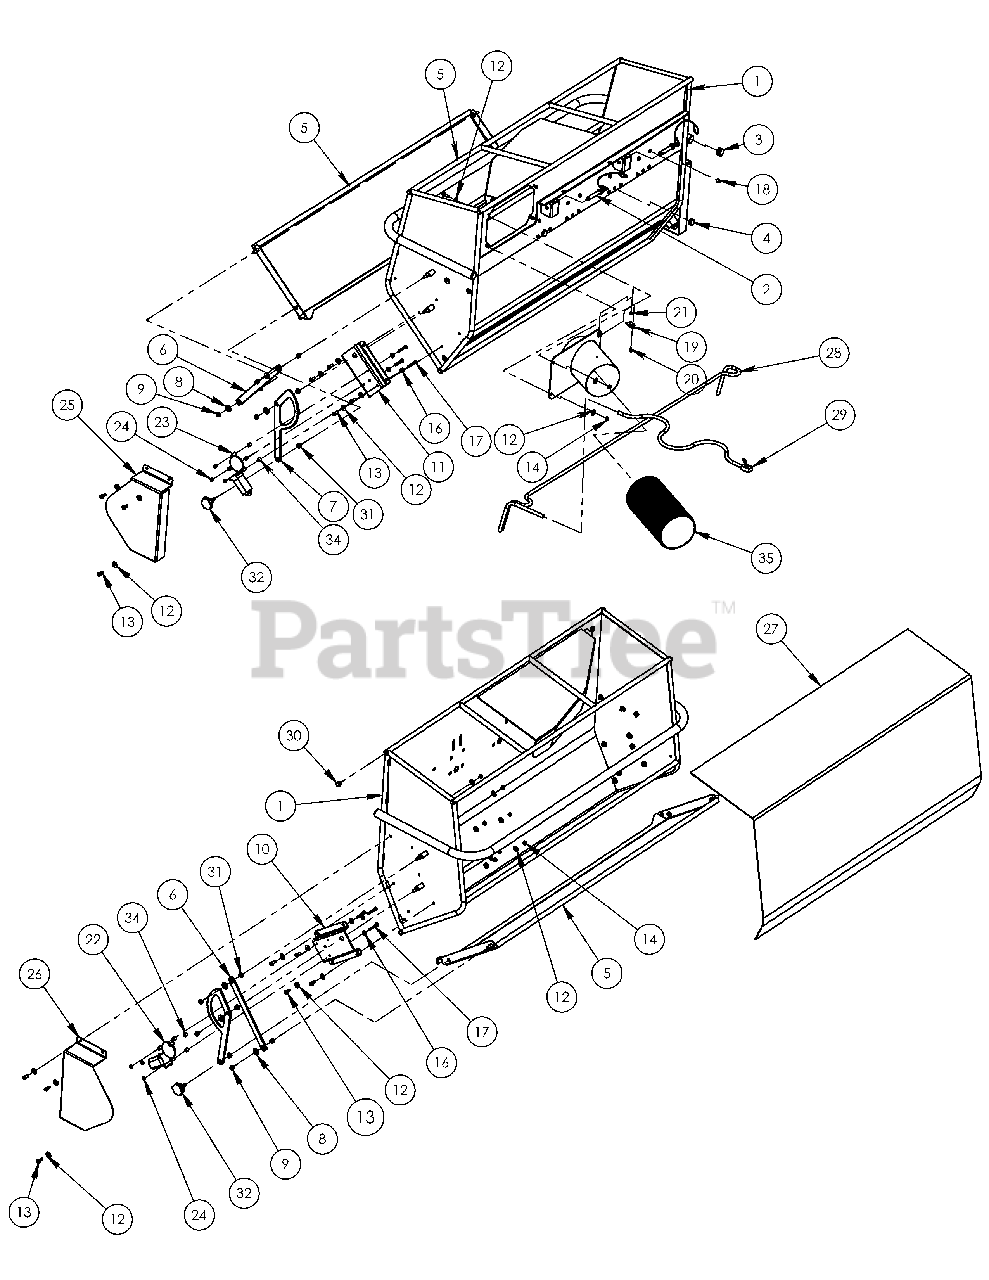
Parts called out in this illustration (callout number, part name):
1	DEDICATED DUMP FRAME 54"
2	1/2 DETENT PIN 2.5" LONG
3	1.25" HOLE PLUG, PLASTIC
4	RUBBER BUMPER
5	GATE ASSEMBLY
6	MASTER LINK
7	DFS ELECTRIC DRIVE RING-GEAR
8	3/8 Washer SAE
9	3/8-16 NYLOCK NUT
10	MOTOR ADAPTER PLATE
11	MOTOR ADAPTER PLATE
12	5/16" Flat Washer
13	CAP SCREW 5/16-18 x .75
14	5/16-18 Nylon Insert Nut
15	6" 3-BAG INLET TUBE
16	1/4" USS WASHER
17	CAP SCREW 1/4-20 x 1 3/4
18	PLUG, HOLE 7/16
19	SPRING CLIP
20	#10 x 3/4 SCREW
21	#10-24 Nylon Insert Nut
22	ELETRIC MOTOR, LEFT HAND
23	ELETRIC MOTOR, RIGHT HAND
24	1/4-20 Nylon Insert Nut
25	DFS MOTOR GUARD, Right
26	DFS MOTOR GUARD, Left
27	DDFS FABRIC COVERING
28	DFS 3-BAG WIRING HARNESS
29	DFS IMPLEMENT WIRING HARNESS
30	3/4" HOLE PLUG, PLASTIC
31	PLASTIC FLANGE BUSHING, 1/2"ID x 5/8" OD
32	DFS Release Knob
33	BUSHING, 1/2" OD x 3/8" ID x 1/2"Lg.
34	MOTOR OFFSET BOSS
